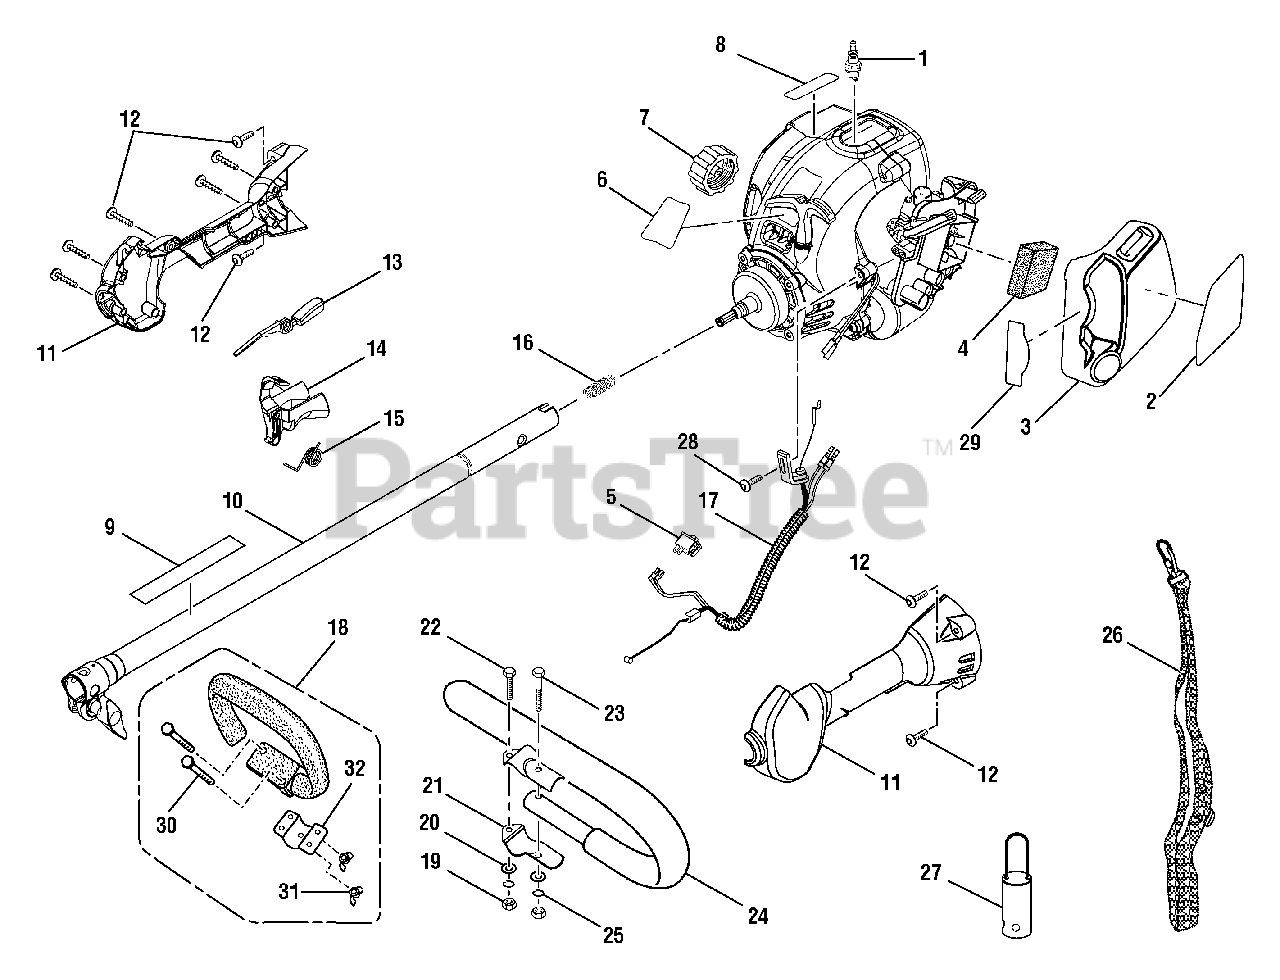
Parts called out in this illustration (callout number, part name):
1	SPARK PLUG (CHAMPION RCJ4)
2	STARTING LABEL
3	AIR BOX COVER
4	AIR FILTER ELEMENT
5	SWITCH (MOMENTARY CONTACT)
6	MODEL LABEL (CS30)
7	FUEL CAP ASSEMBLY
8	LOGO PLATE
9	WARNING DECAL (CS30 AND SS30)
10	UPPER BOOM ASSEMBLY (CS30 AND SS30)
11	CONTROL HANDLE ASSEMBLY
12	SCREW (10-14 X 1 in.)
13	TRIGGER LOCK
14	TRIGGER
15	TORSION SPRING
16	COMPRESSION SPRING
17	THROTTLE AND LEAD ASSEMBLY
18	FRONT HANDLE ASSEMBLY (CS30 AND SS30)
19	HEX NUT (1/4-20) (BC30)
20	WASHER (BC30)
21	HANDLE BAR CLAMP (BC30)
22	BOLT (1/4-20 X 1 in. HEX HD.) (BC30)
23	BOLT (1/4-20 X 1-1/2 in. HEX HD.) (BC30)
24	"J" HANDLE AND GRIP (BC30)
25	LOCK WASHER (BC30)
26	SHOULDER STRAP (BC30)
27	HANGER CAP
28	SCREW (10-24 X 7/8 in.)
29	CHOKE LABEL
30	BOLT (M5 X 30 mm HEX HD.) (CS30 AND SS30)
31	WING NUT (M5)
32	HANDLE BAR CLAMP (CS30 AND SS30)
